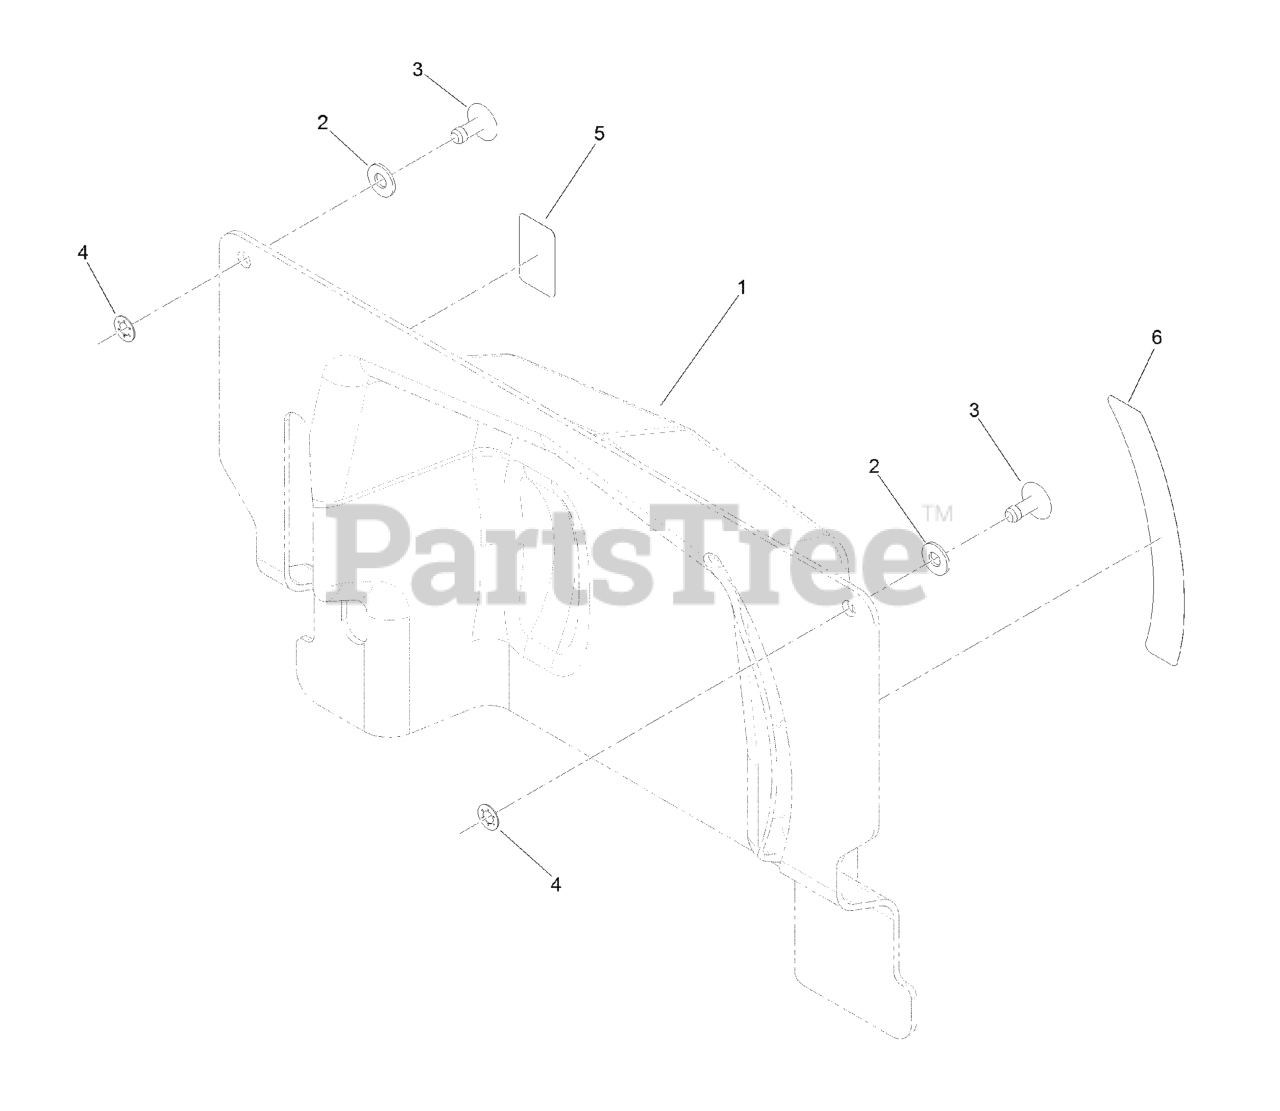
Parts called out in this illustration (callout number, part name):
1	Cover-Transaxle
2	WASHER-FLAT
3	STUD-1/4 TURN
4	RETAINER-STUD
5	DECAL-BRAKE, PARK
6	DECAL-RELEASE, DRIVE
